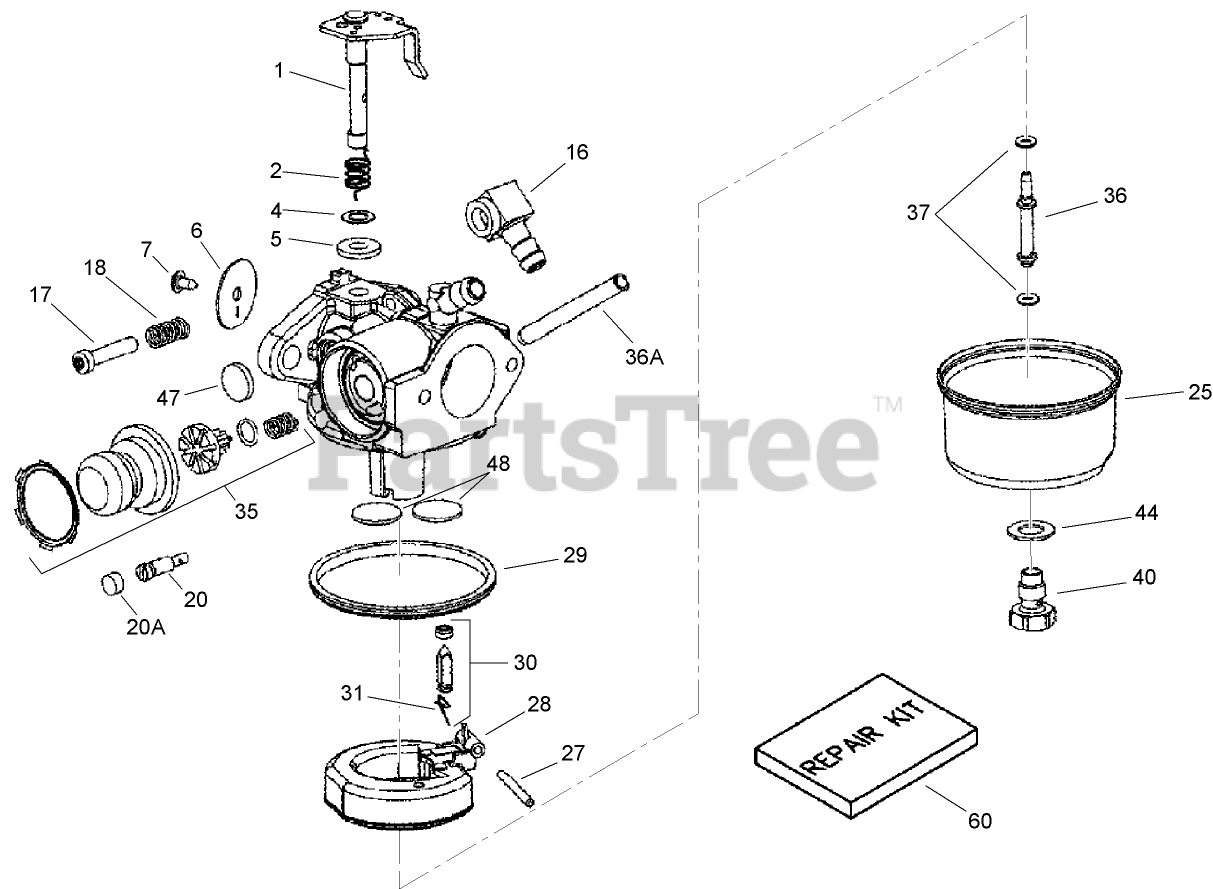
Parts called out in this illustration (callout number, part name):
1	Throttle Shaft and Lever ASM
2	Spring-Return, Throttle
4	Washer-Seal, Dust
5	Seal-Dust
6	Shutter-Throttle
7	Screw-Shutter
16	Fitting-Fuel
17	Screw-Throttle Crack and Idle Speed
18	Spring-Tension
20	Screw-Restrictor, Idle
20A	Cap-Screw, Restrictor Idle
25	Bowl-Float (no drain)
27	Shaft-Float
28	Float (Plastic)
29	O Ring-Bowl, Float
30	Inlet Needle, Seat and Clip ASM (Includes 31)
31	Clip-Spring
35	Primer Bulb and Valve Repair Kit
36	Tube-Nozzle, Main
36A	Tube-Carburetor
37	O-Ring
40	Nut-Bowl, High Speed
44	Washer-Nut, Bowl
47	Plug-Welch, Idle Mixture Well
48	Plug-Welch, Atmospheric Vent
60	Carburetor Repair Kit
